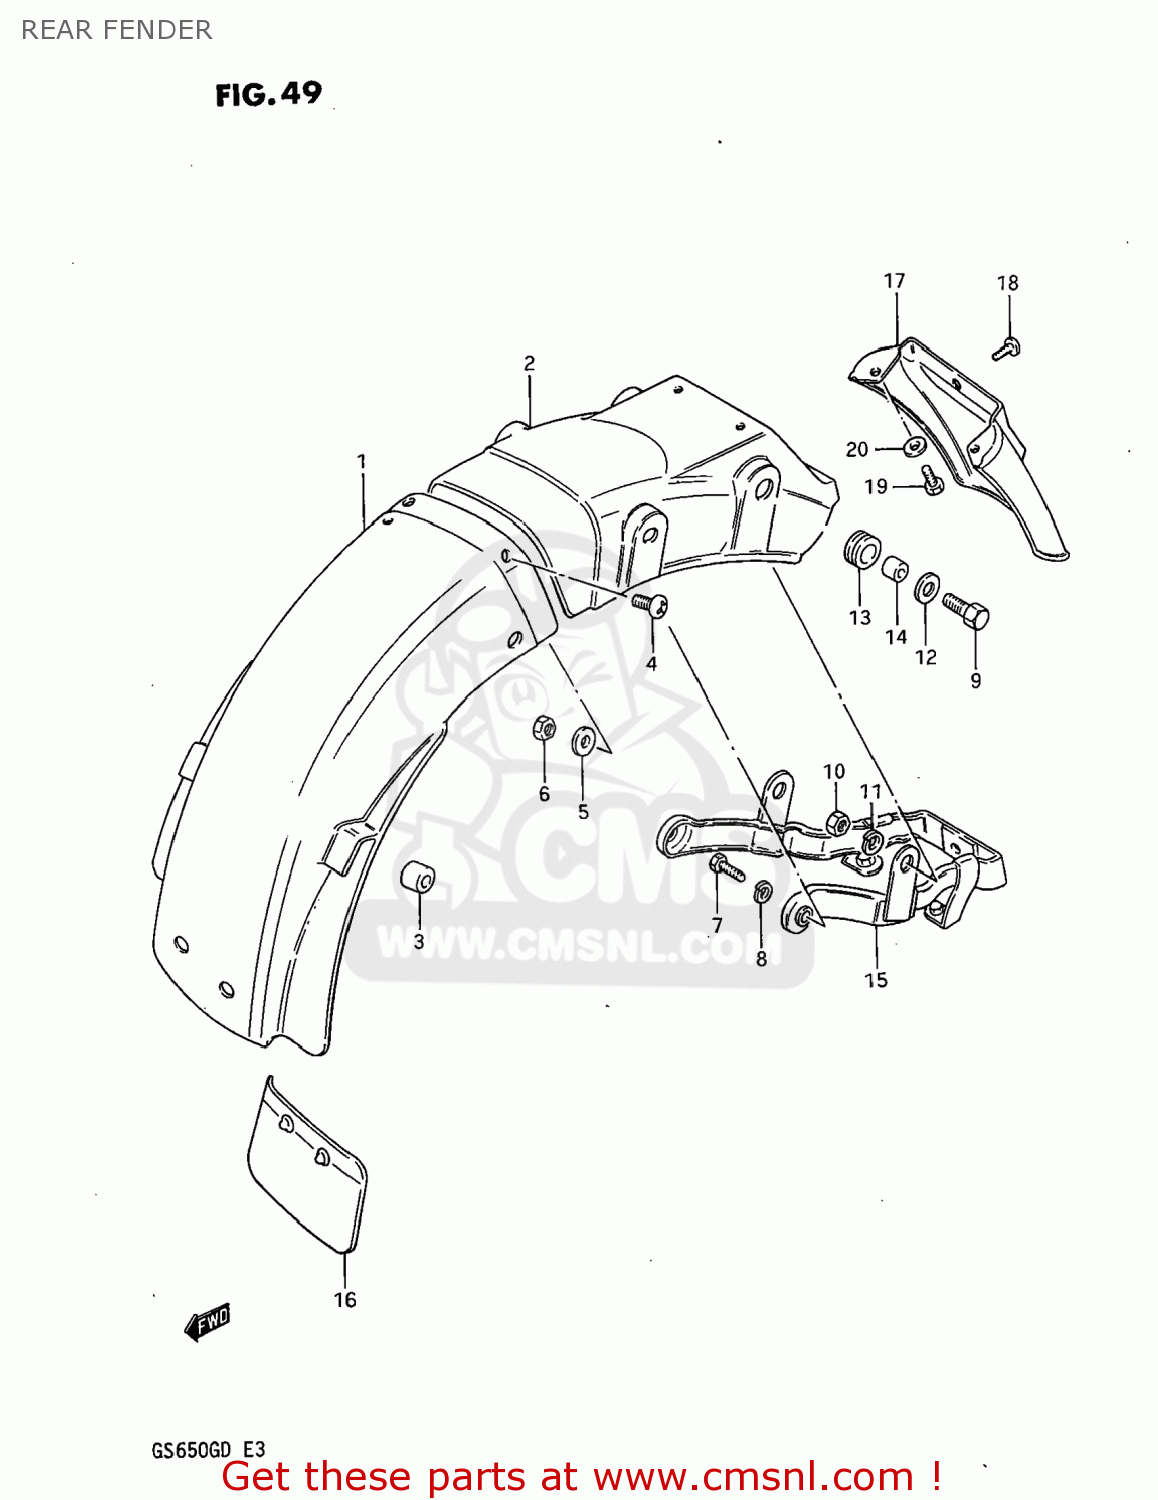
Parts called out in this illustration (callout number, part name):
1	BODY,REAR FENDER,REAR
2	BODY,REAR FENDER,REAR
3	CUSHION
4	SCREW
5	WASHER (5.5X16X1.2)
6	NUT
7	BOLT, UPPER
8	LOCK WASHER
9	BOLT (8X30)
10	NUT
11	LOCK WASHER
12	WASHER
13	CUSHION
14	SPACER (8.2X12X7.5)
15	REINFORCEMENT,REAR FENDER
16	GUIDE,RR FENDER MUD
17	EXTENSION,RR FENDER
18	SCREW
19	BOLT, UPPER
20	WASHER (6.5X20X1.2)
